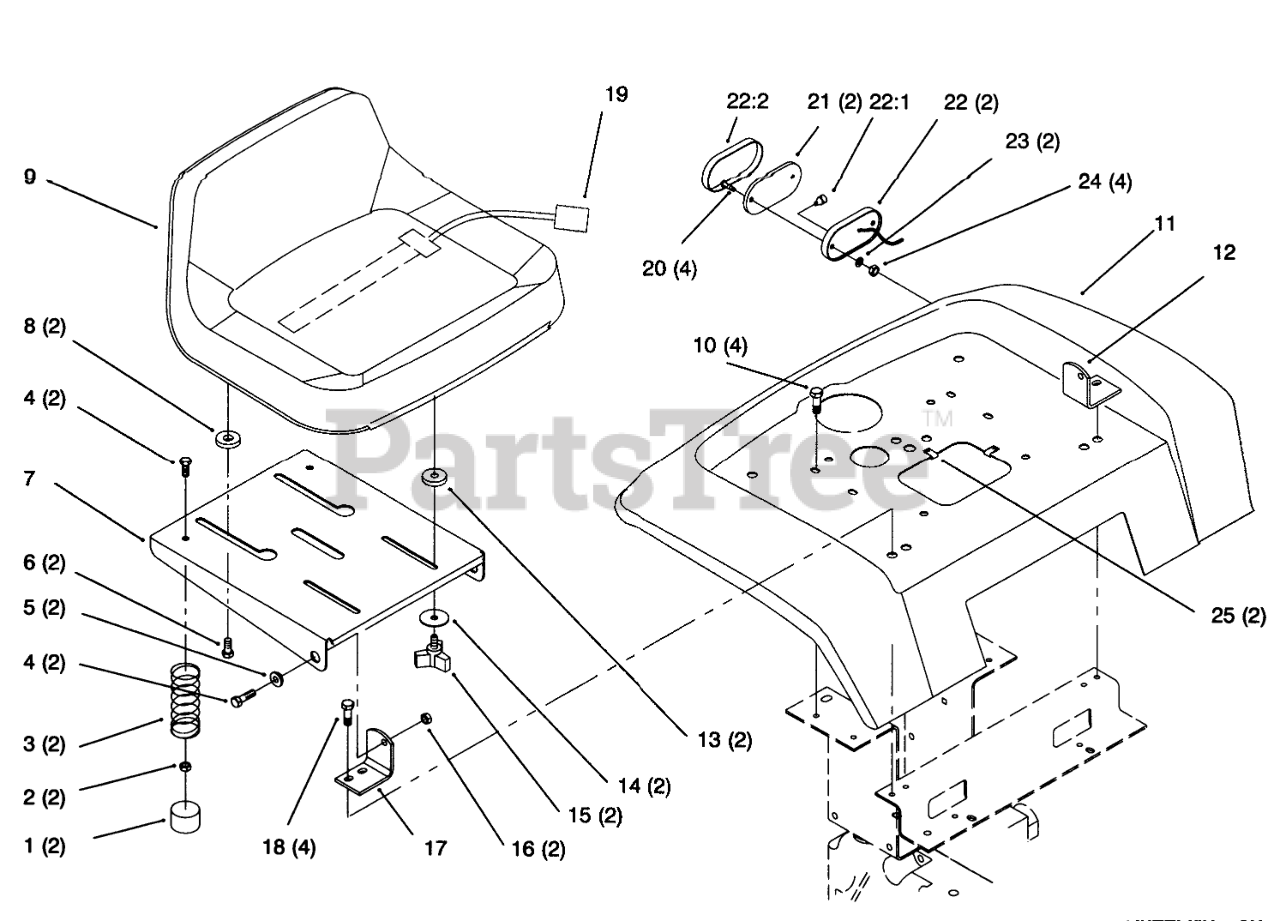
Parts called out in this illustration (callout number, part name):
1	CAP-PROTECTOR
2	NUT-LOCK, NI
3	SPRING-COMPRESSION
4	SCREW-HH
5	BUSHING
6	BOLT-SHOULDER
7	SUPPORT - SEAT (BLACK)
8	SPACER-NYLON
9	SEAT-V-511
10	Bolt
12	BRACKET-PIVOT, LH
13	SPACER-NYLON
14	WASHER
16	NUT-LOCK, NI
17	BRACKET-PIVOT, RH
18	SCREW-HWHTF
19	SWITCH-SEAT
20	SCREW-PPH
21	Reflector
24	NUT-LOCK, NI
28	Decal-Rear Fender
30	DECAL - WHEELHORSE
